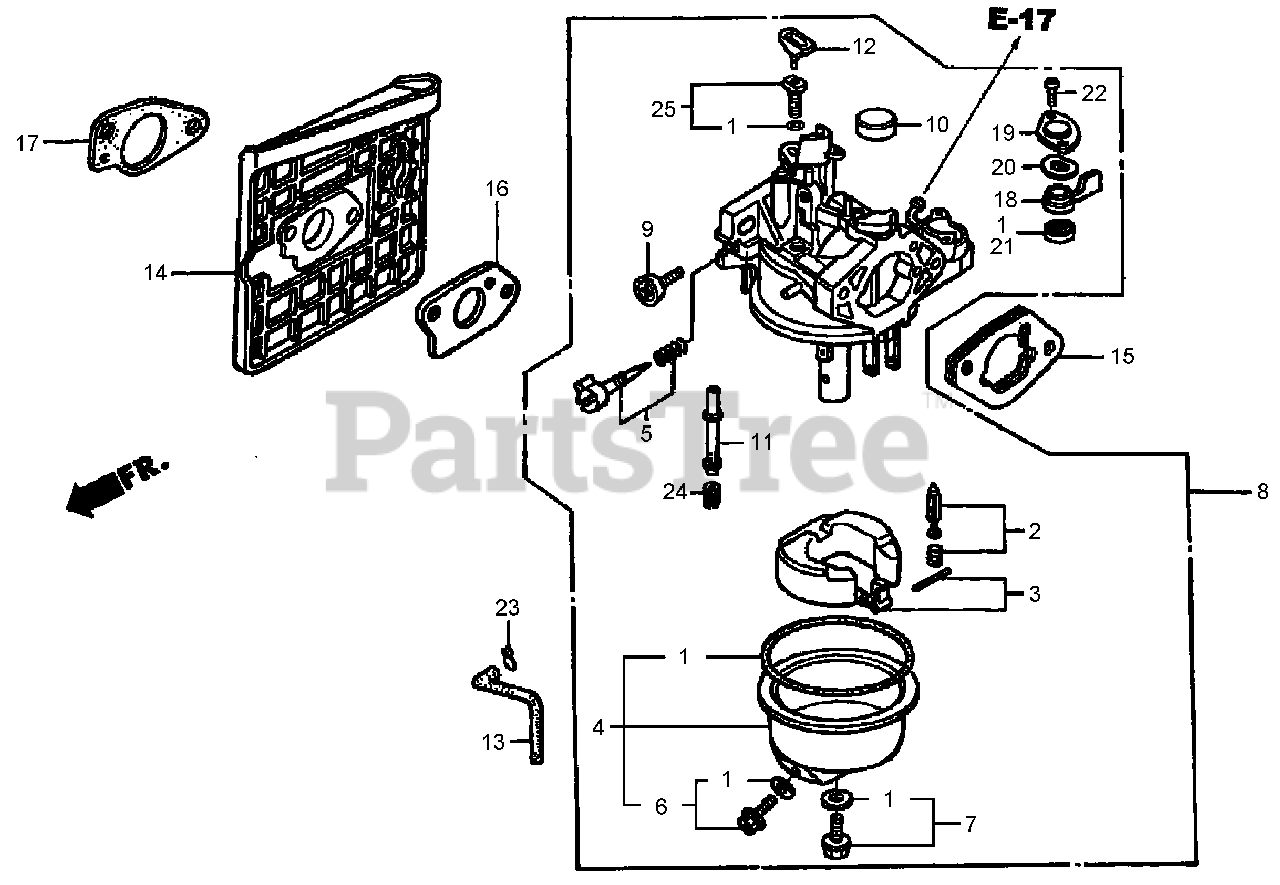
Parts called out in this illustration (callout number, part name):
1	GASKET SET
2	VALVE SET-FLOAT
3	FLOAT SET
4	CHAMBER SET-FLOAT
5	PILOT SCREW SET
6	DRAIN SCREW SET
7	SCREW SET
8	CARBURETOR ASM (BE86P A)
9	SCREW- STOP, THROTTLE
10	CAP-DUST, CHOKE LEVER
11	NOZZLE-MAIN
12	COLLAR-SET
13	TUBE-VENT, AIR (75MM)
14	INSULATOR-CARBURETOR
15	SPACER-CARBURETOR
16	GASKET-CARBURETOR
17	GASKET-INSULATOR
18	LEVER-VALVE
19	PLATE-SETTING, LEVER
20	SPRING-LEVER, PETCOCK
21	GASKET-PETCOCK
22	SCREW-PAN (3X6)
23	CLIP-TUBE (B8)
24	JET-MAIN (No. 88)
24	JET-MAIN (No. 90)
24	JET-MAIN (No. 92)
25	JET SET-PILOT (No. 40)
